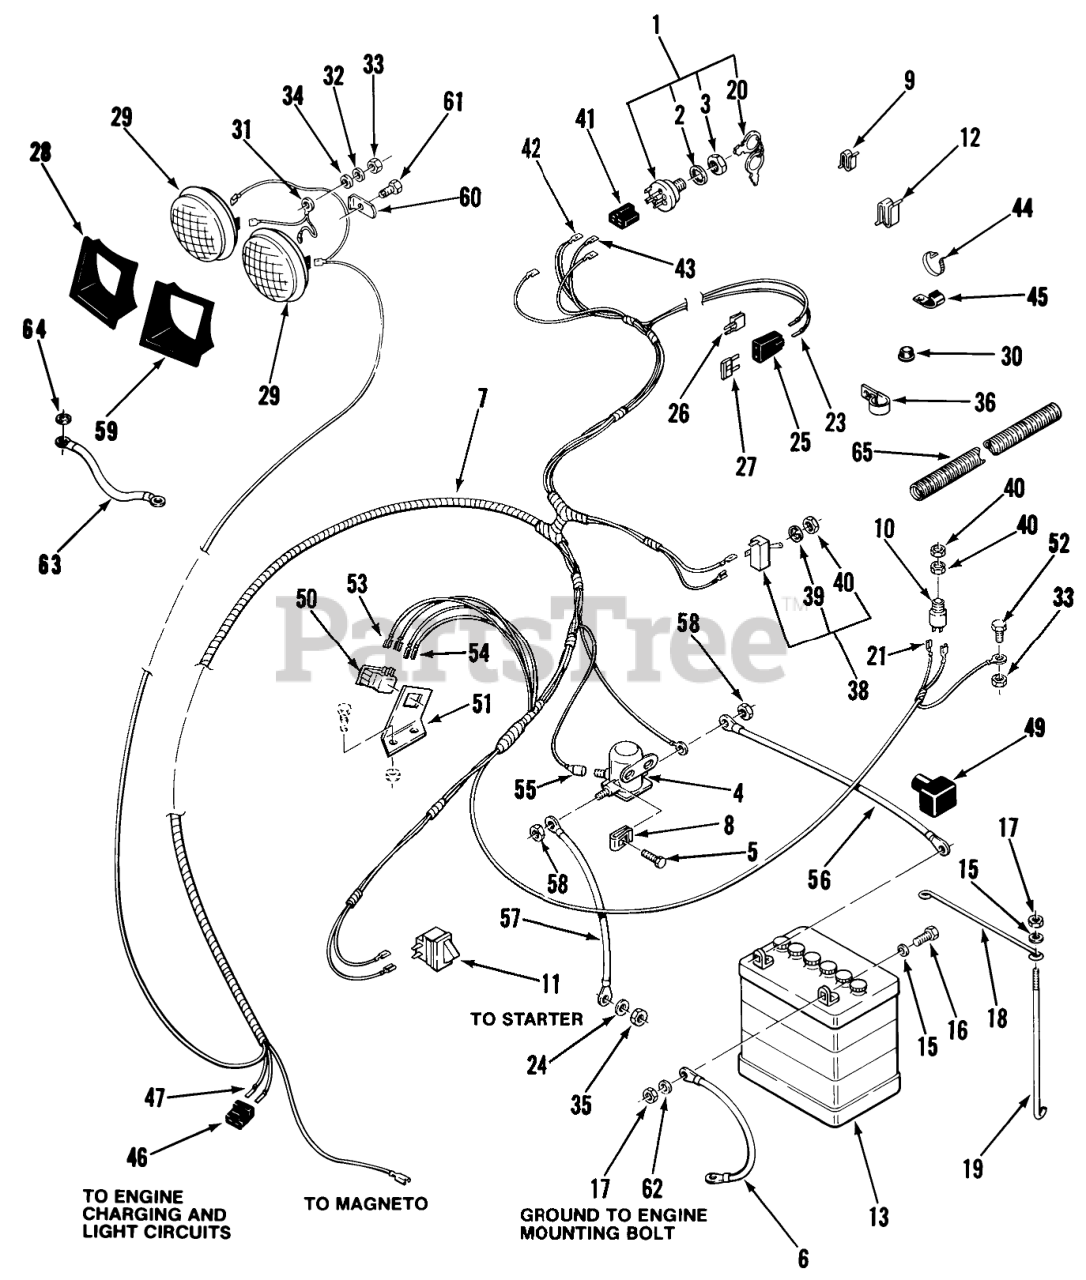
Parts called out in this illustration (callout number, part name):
1	ASSY-SWITCH IGNITION
2	LOCKWASHER
4	Solenoid
5	Screw
6	Wire
7	Wiring Harness Assy 216-5 Only
7	Wiring Harness Assy B-115 Only
7	Wiring Harness Assy LT-1032 Only
7	HARNESS-WIRING
8	Speed Nut
9	SPEED CLIP
10	SWITCH-SEAT
10	SWITCH-BALL
11	SWITCH INTERLOCK
12	CLIP-CABLE
13	Battery
16	Bolt
17	Nut
18	ROD-HOLD DOWN
20	Key-EL
21	Connector
23	TERMINAL-FUSE
24	Washer
25	AUTO-FUSEBLOCK TERM
27	FUSE-BLADE, 15 AMP
28	BEZEL-HEADLIGHT, RH
29	HEADLAMP
30	BUSHING-NYLON .75
31	LIGHT GROUND WIRE
32	WASHER 5/16 SAE
33	Nut
34	Washer-Lock
35	Nut
36	CLAMP
38	SWITCH-LIGHTS
39	TAB-WASHER
40	NUT-HEX, SPECIAL
41	CONNECTOR-5 WAY-SERV
42	TERMINAL-TAB RCPT
43	Terminal
44	Cable Tie
45	CLIP
46	Conn Body Part of 7
47	Terminal
49	Boot
50	PTO Interlock Switch
51	BRACKET-SWITCH R
52	Bolt
53	Terminal
54	Wire Terminal (Part of 1)
55	Terminal Part of 5
56	Wire
57	Starter To Solenoid Cable 23.0 in. (58.4 cm) B-115 Only
57	Starter To Solenoid Cable 16.0 in. (40.6 cm) 216-5 Only
57	Solenoid To Engine Starter Cable
58	NUT-HEX, SPECIAL
59	BEZEL-HEADLIGHT, LH
60	LOCK-HEADLIGHT
61	Bolt
62	Washer
63	WIRE GROUND
64	Washer-Lock
65	Conduit 216-5 Only
